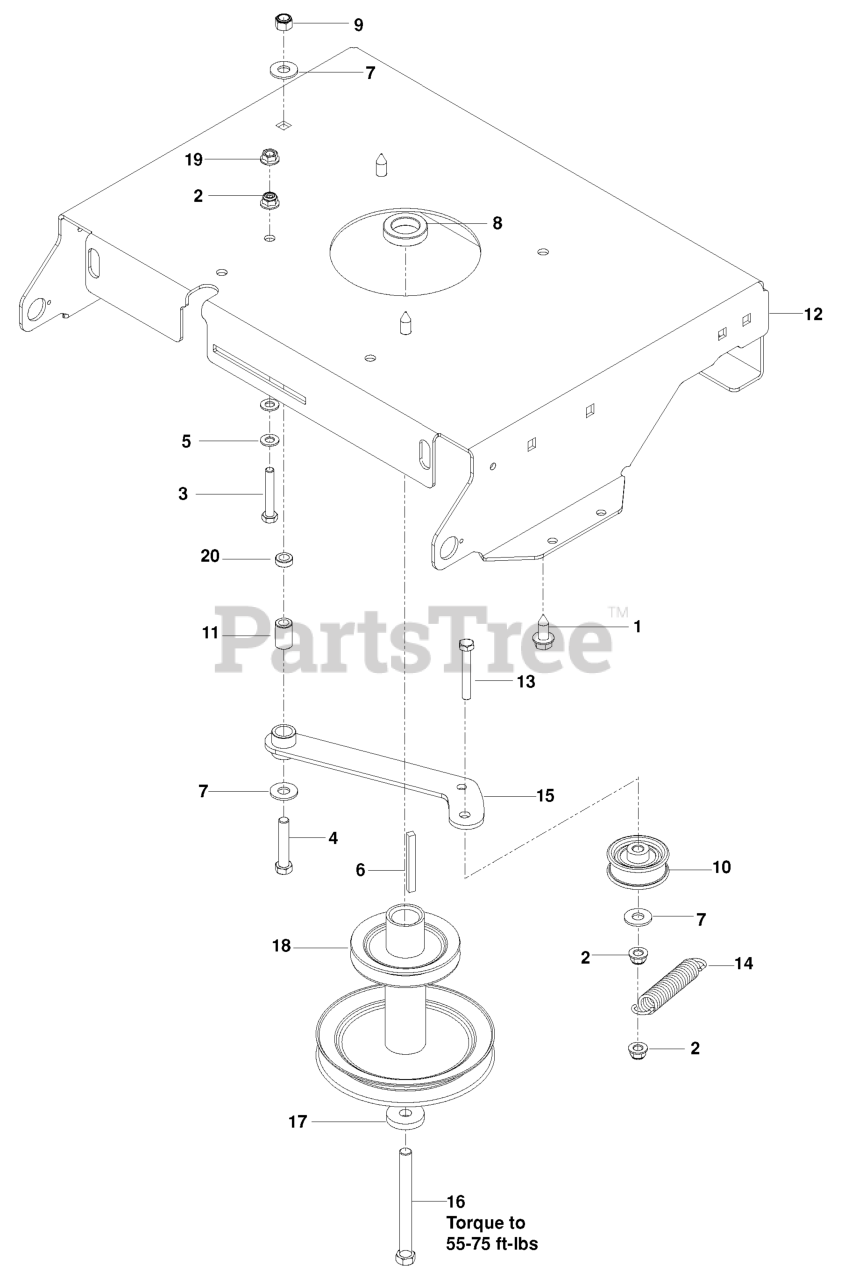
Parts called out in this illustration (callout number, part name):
1	HHFS 3/8-16 X 1.0 THD FORMING
2	5/16-18 NYLOC FLANGE NUT
3	HCS 5/16-18X2
4	HCS 3/8C X 2
5	FLAT WASHER 5/16 SAE
6	KEY 1/4 SQ X 2-1/2
7	WASHER 3/8 FLAT
9	NUT HEX 3/8-16 NYLON, THIN
10	PULLEY IDLER
12	PLATE, ENGINE, ORG
13	HCS 5/16-18 X 2 1/2 TPBLT
14	SPRING - 3.50
15	!DLER ARM WLDMNT, BLACK
16	HCS 7/16-20 X 4 GR5 ZD
17	WASHER .43X1.38X.25
18	PULLEY, ENGINE 6.5
19	NUT 5/16C WHIZ
20	WASHER 3/8 X 3/4 X .187 TK
